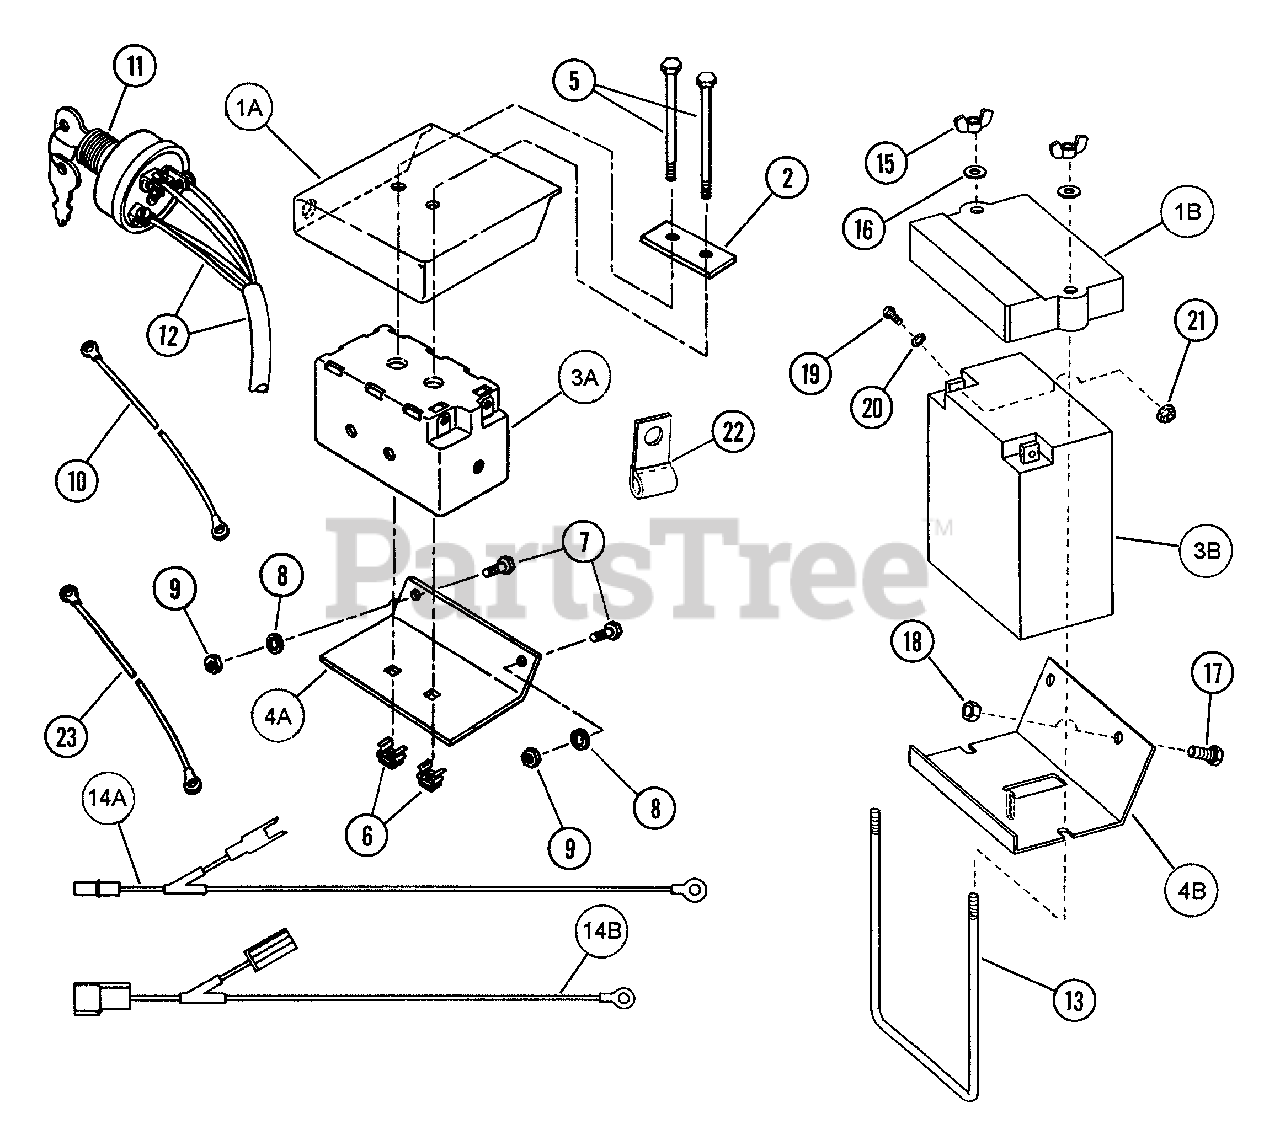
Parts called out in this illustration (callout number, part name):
1A	COVER, Battery
1B	COVER, Battery
2	PLATE, Hold Down
3A	BATTERY, 12 V Sealed Lead Acid (5 A. H.
3B	BATTERY, 12 V (12 A.H.)
4A	BRACKET, Battery Mtg.
4B	BRACKET, Battery Mtg.
5	SCREW, #10-32x4-1/2"
6	CLIP-NUT, #10-32
7	SCREW, 5/16-18 x 3/4" Hex Head Cap, Grade 2
8	WASHER, 5/16 Internal Tooth Lock
9	NUT, 5/16-18 Hex, Grade B or 5
10	WIRE, Negative
11	SWITCH, Electric Start
12	HARNESS, Wiring
13	CLAMP, Battery
14A	HARNESS, Charging (B&S)
14B	HARNESS, Charging (Tec.)
15	WING-NUT, 1/4-20
16	WASHER, 1/4 SAE
17	SCREW, 5/16-18 x 5/8" Hex Head Cap, Grade 5
18	NUT, 5/16-18 Hex Center Lock
19	SCREW, #10-24 x 1/2" Hex Head Cap
20	WASHER, #10 External Tooth Lock
21	NUT, #10-24 Hex "Whiz Lock"
22	HARNESS CLIP
23	WIRE, Battery to Switch
